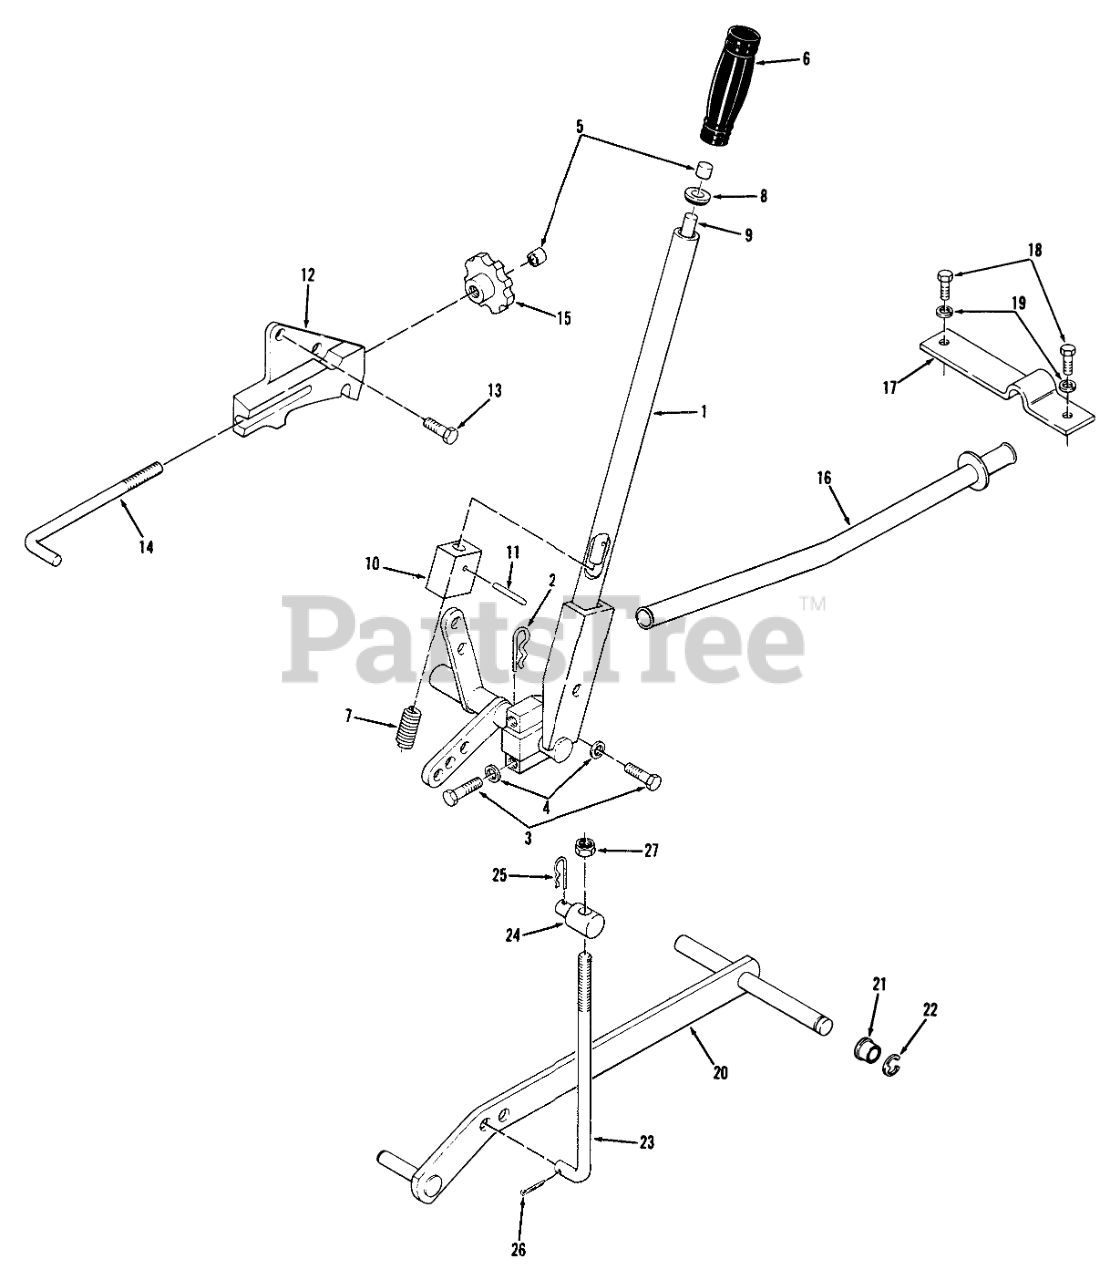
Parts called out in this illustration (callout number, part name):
1	Lift Lever
2	Hairpin
3	H H C S
4	Lockwasher
5	CAP-ROD, PLUNGER
6	HANDGRIP
7	SPRING-COMPRESSION
8	Guide-Rod
9	PLUNGER ROD
10	LOWER PLUNGER R
11	Roll Pin
12	Quadrant
13	Bolt
14	ROD-LIFT CONTROL
15	KNOB-LIFT CONTROL
16	TUBE ASSY COMPLET R
17	Clamp-Conduit
18	Bolt
19	LOCKWASHER
20	ASSY LIFT BAR R
21	BUSHING
22	E Ring
23	ROD-LIFT
24	TRUNNION-LIFT
25	Hairpin
26	Cotter Pin
27	NUT
